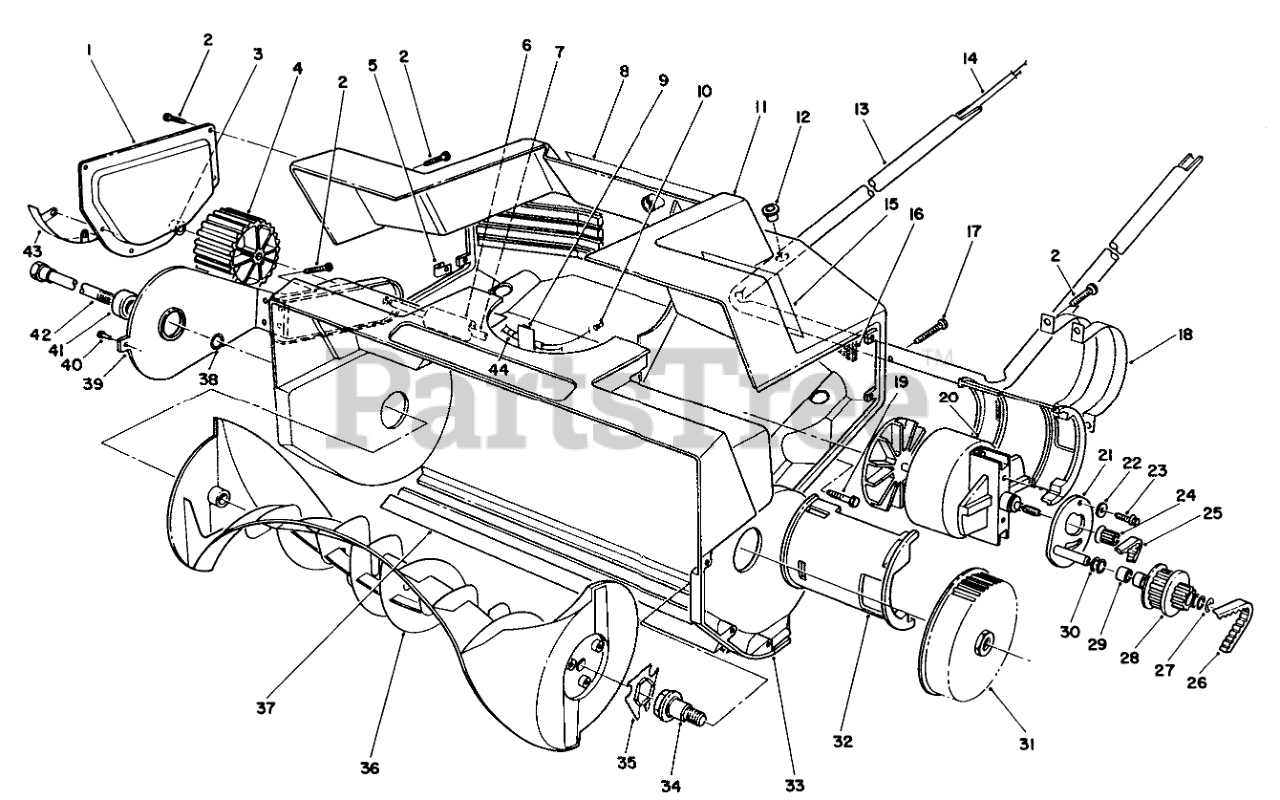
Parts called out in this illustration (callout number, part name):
1	PLATE - SIDE, PAINTED
2	Screw
3	PUSHNUT-CAP, WASHER
4	Wheel
5	U-CLIP
6	SLEEVE, AXLE
7	Shaft-Axle
8	Decal-Danger
9	CORD CLIP
10	Connector
11	Shroud-Housing
12	BUSHING
13	Tube-Lower Handle
14	WIRE HARNESS-TORO 1800
15	DECAL - WARNING
16	Filter-Foam
17	Screw-Pan Head
18	Strap-Motor
19	SCREW-HH
20	Motor
21	IDLER BRACKET ASSEMBLY
22	WASHER-PLAIN
23	SCREW-HWHTF
24	PULLEY - DRIVER
25	BELT-PULLEY, IDLER/DRIVER
26	BELT-DRIVE
27	RING-RETAINING
28	Pulley-Idler (Incl. Ref. #29)
29	Bearing-Needle
30	WASHER-THRUST
31	PULLEY, DRIVEN
32	Clamp-Motor Bracket
33	HOUSING, ROTOR, 1800
34	Shaft-Driver, Rotor
35	Coupler-Rotor
36	Rotor
37	Scraper
38	WASHER-THRUST
39	Bracket-Wheel (Incl. Ref. #41)
40	RIVET-POP
41	Bearing-Ball
42	Shaft-Rotor
43	Skid-Housing
44	Relief-Strain
